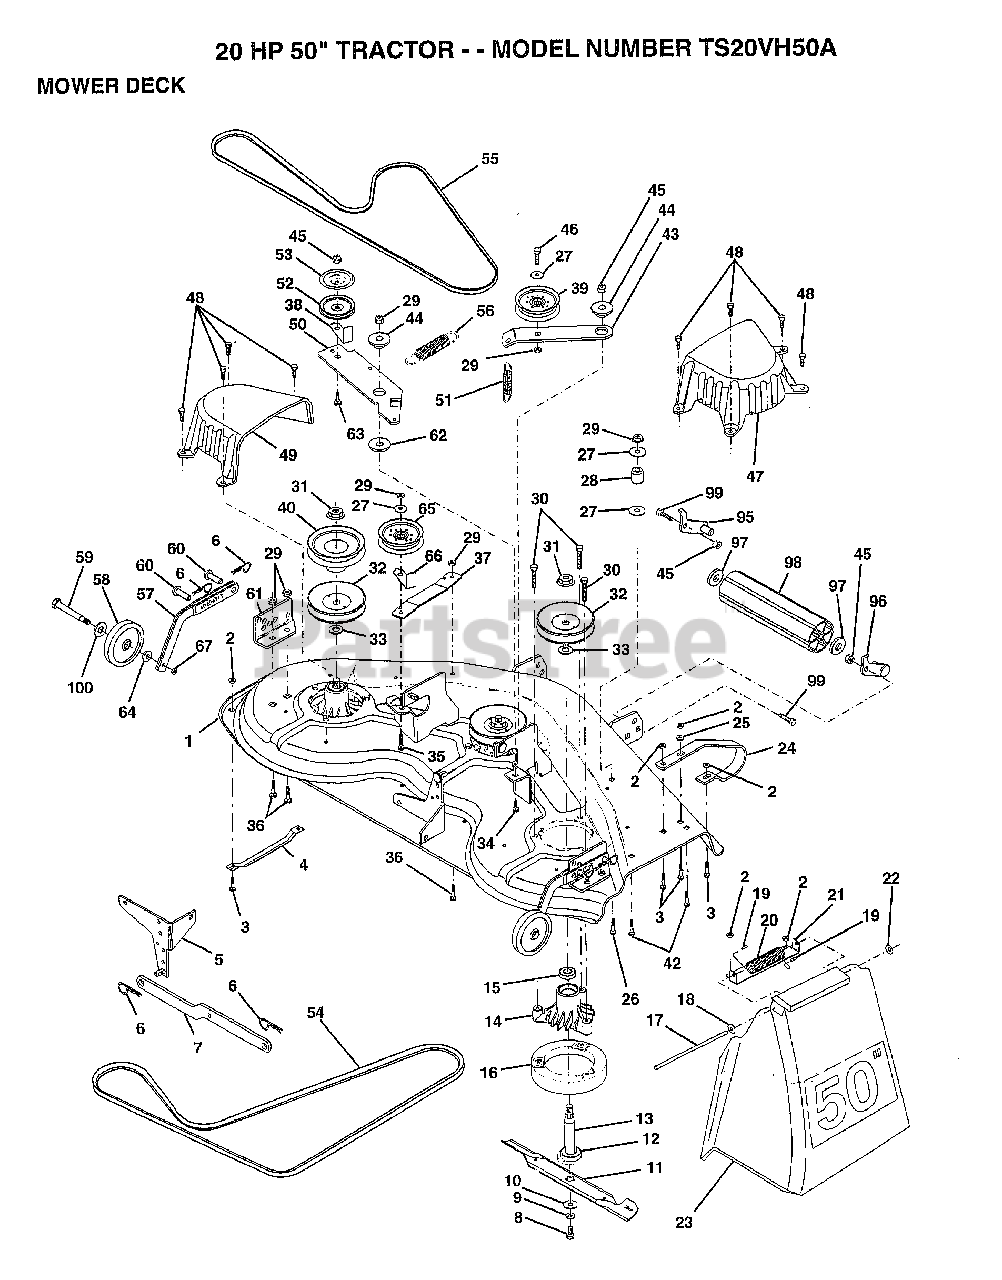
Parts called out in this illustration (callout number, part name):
1	DECK ASM MWR 50VT
2	NUT
4	RUNNER-LH M
5	BRKT.ASM.SW.44/50
8	BLADE BOLT
10	WASHER.HARD.BLADE
11	"BLADE.50"" HD"
12	BEARING.BALL
13	SHAFT.ASM.W/BRNG
14	HOUSING.MAND.44.V
15	BEARING
16	STRIPPER RND MWR
17	ROD-HINGE T
18	WASHER
19	CAP-SLEEVE LT
20	SPRING TORSION
21	BRKT DEFLECTOR
22	NUT PUSH M
23	DEFLECTOR
24	"RUNNER RH 50"" DK"
25	WASHER M
26	BOLT
27	WASHER
29	NUT
33	WASHER
34	BOLT.3/8-14X1.25
35	BOLT
36	BOLT D
37	STIFFENER.ARM.IDL
39	FLAT IDLER PULLEY
40	"PULLEY.DRIVEN.44"""
42	BOLT
43	"ARM.IDLER.SEC.44"""
44	SPACER RETAINER
47	"COVER.MAND.RH.44"""
48	SCREW.1/4-20X5/8
49	COVER.MANDREL.LH
50	ARM.IDLER.PRIMARY
51	"SPRING.SEC.44""VEN"
52	PULLEY.IDLER.VGRO
53	SHIELD.IDLER.44.V
54	BELT V PRIM 50
55	BELT.V.GDRIVE.95
56	SPRING.EXT.DECK.
57	BAR.ASM.GUAGE.WHL
58	WHEEL.GAGE.BLK.PL
59	BOLT M
60	PIN.CLEVIS
61	BRACKET.GUAGE.WHL
62	HARDENED WASHER
63	BOLT.3/8-16X1.50
64	WASHER
65	IDLER-FLAT T
67	LOCKNUT
97	WASHER
99	BOLT
100	WASHER
